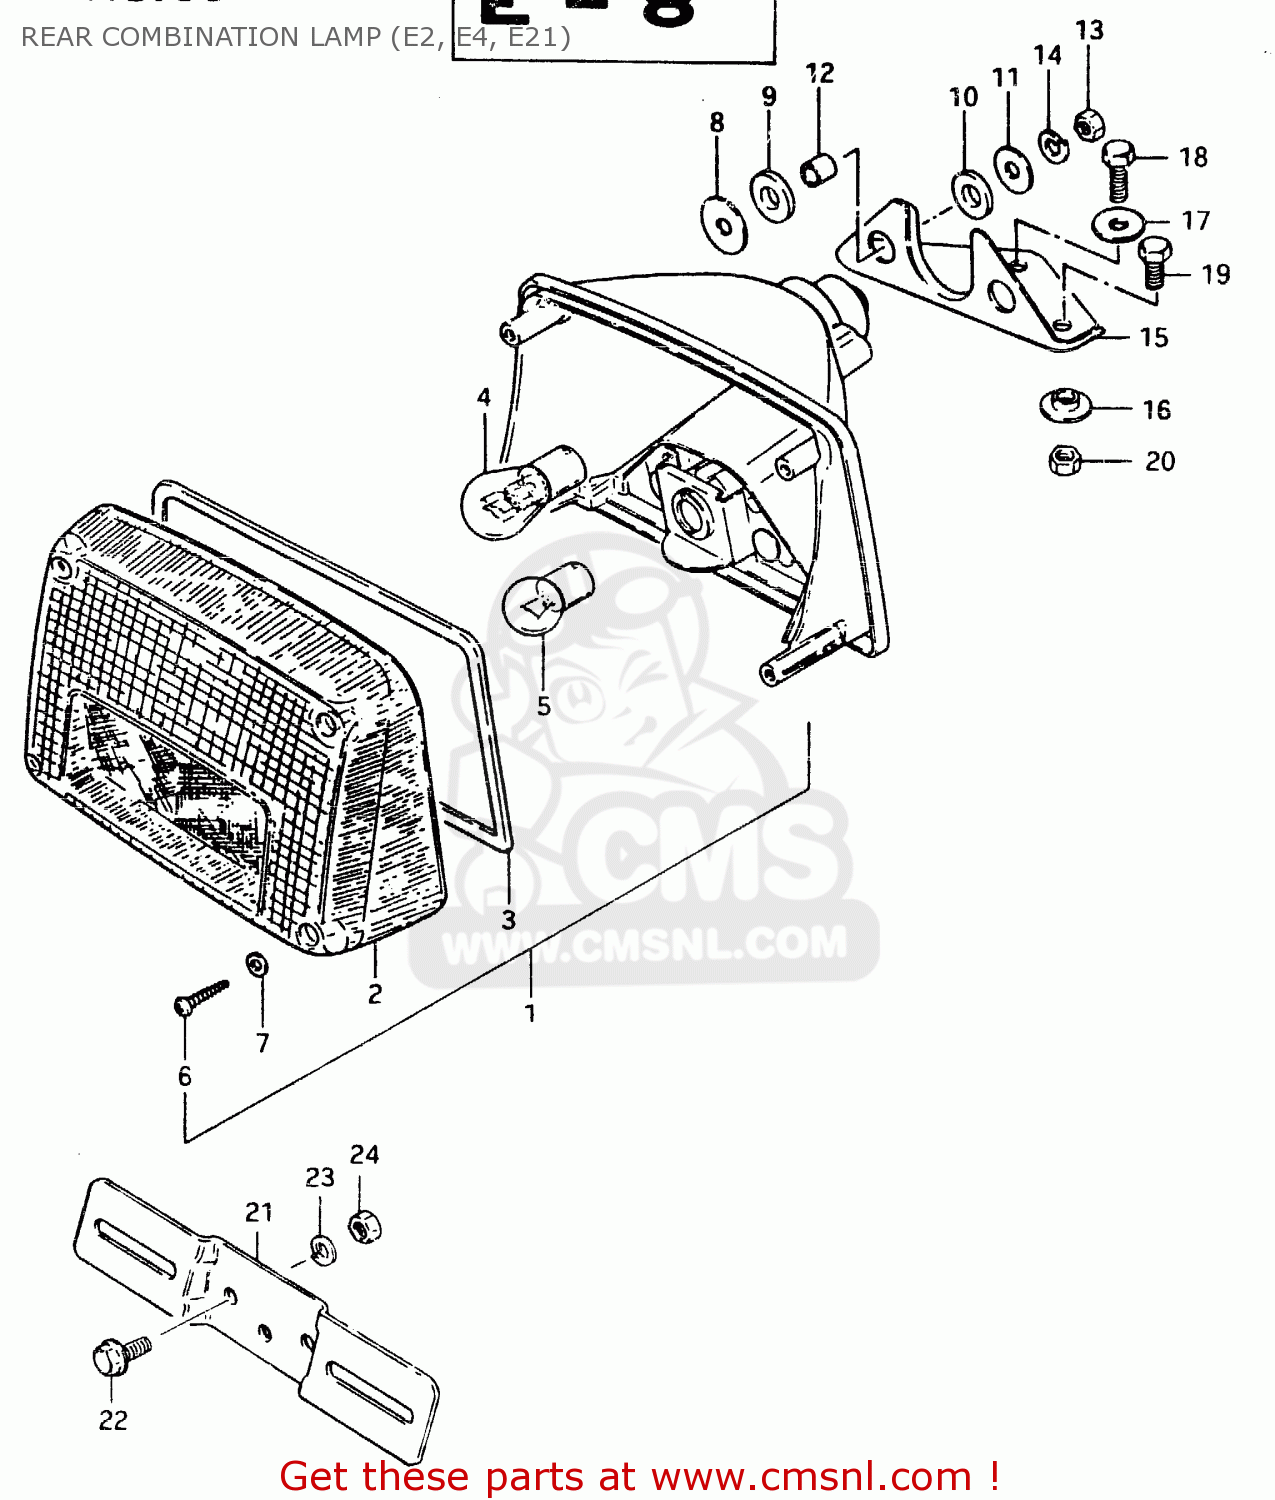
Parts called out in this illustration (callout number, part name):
1	LAMP, REAR COMBINATION
2	LENS,RR COMBI
3	GASKET (NAS)
4	BULB 12V21/5W
5	BULB
6	SCREW,REAR COMBINATION LAMP
7	GASKET (NAS)
8	WASHER
9	CUSHION
10	CUSHION
11	WASHER(6,5X22X1.6)
12	SPACER(6.1X9X7.5)
13	NUT
14	LOCK WASHER
15	BRACKET,RR COMBINATION LAMP
16	WASHER
17	WASHER
18	BOLT
19	BOLT, UPPER
20	NUT 6MM
21	BRACKET, LICENSE PLATE
22	BOLT
23	LOCK WASHER
24	NUT
